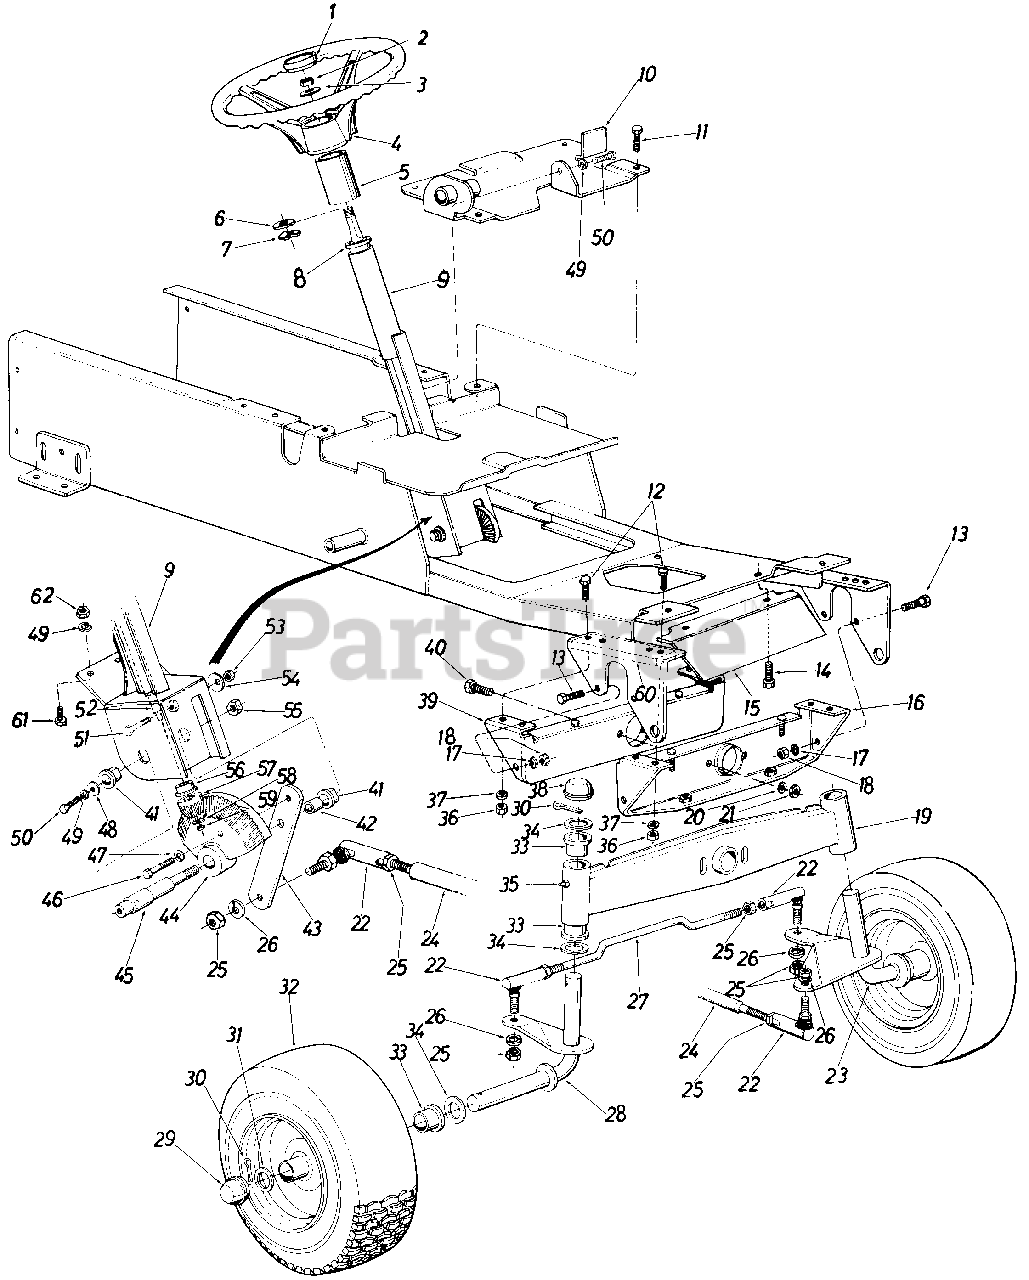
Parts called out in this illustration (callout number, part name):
1	Steering Wheel Cap
2	Hex Cent. L-Nut 5/16-18 Thd.
4	Steering Wheel
5	Steering Tube Outer
6	Double "D" Fl-Wash.
7	Wave Wash. .660 I.D. x .88 0 O.D.
8	Ball Brg. .63 I.D. x 1.38 O.D.
10	Dash Panel Base Plate Ass'y.
11	Hex Self-Tap Scr. 3/8-16 x .75" Lg.
12	Hex Scr. 3/8-16 x 1.50" Lg.*
13	Hex Scr. 3/8-16 x 1.00" Lg.
14	Hex Wash. S.F. Tap Scr. 3/8-16 x 1.25" Lg.
15	Dust Shield
18	Hex Nut 3/8-16 Thd.
19	Pivot Bar Ass'y.
20	Bell-Wash. 318" Scr.
21	Hex Cent. L-Nut 3/8-16 Thd.
22	Drag Link End
23	Axle Ass'y. L.H.
25	Hex Nut 1/2-20 Thd.
26	L-Wash. 1/2" Scr.
28	Axle Ass'y. R.H.
30	Cotter Pin 3/16" Dia. x 1.50" Lg.
31	Fl-Wash. 1.00" I.D. x 1.62" O.D.
33	Flange Brg. 1.00" I.D.
34	Fl-Wash. 1.00" I.D. x 1.62" O.D.
35	Grease Fitting
36	Hex Nut 3/8-16 Thd.*
37	L-Wash. 3/8" Scr.*
38	Dust Cover
40	Hex Scr. 3/8-16 x 2.50" Lg.*
41	Flange Brg. w/Flats .753 I.D.
42	Steering Gear Shaft Spacer
43	Steering Arm
44	Bevel Gear
45	Steering Gear Shaft
46	Hex Scr. 3/8-16 x 1.50" Lg.*
47	L-Wash. 3/8" Scr.*
48	Fl-Wash. .406 I.D. x 1.25" O.D.
49	L-Wash. 3/8" Scr.*
50	Hex Scr. 3/8-16 x .75" Lg.*
51	Nylon Hex Scr. 3/8-16 x 1.25" Lg.
52	Steering Shaft
53	Hex Jam Nut 3/8-16 Thd.
54	Bell-Wash. .400 I.D. x 1.13 0 O.D.
55	Hex Ins. L-Nut 1/2-20 Thd.
56	Hex Flange Brg. .630 I.D.
57	Pinion Gear
58	Fl-Wash. 3/8" Dia.
59	Hex Cent. L-Nut 5/16-24 Thd.
62	Hex Nut 3/8-24 Thd.*
